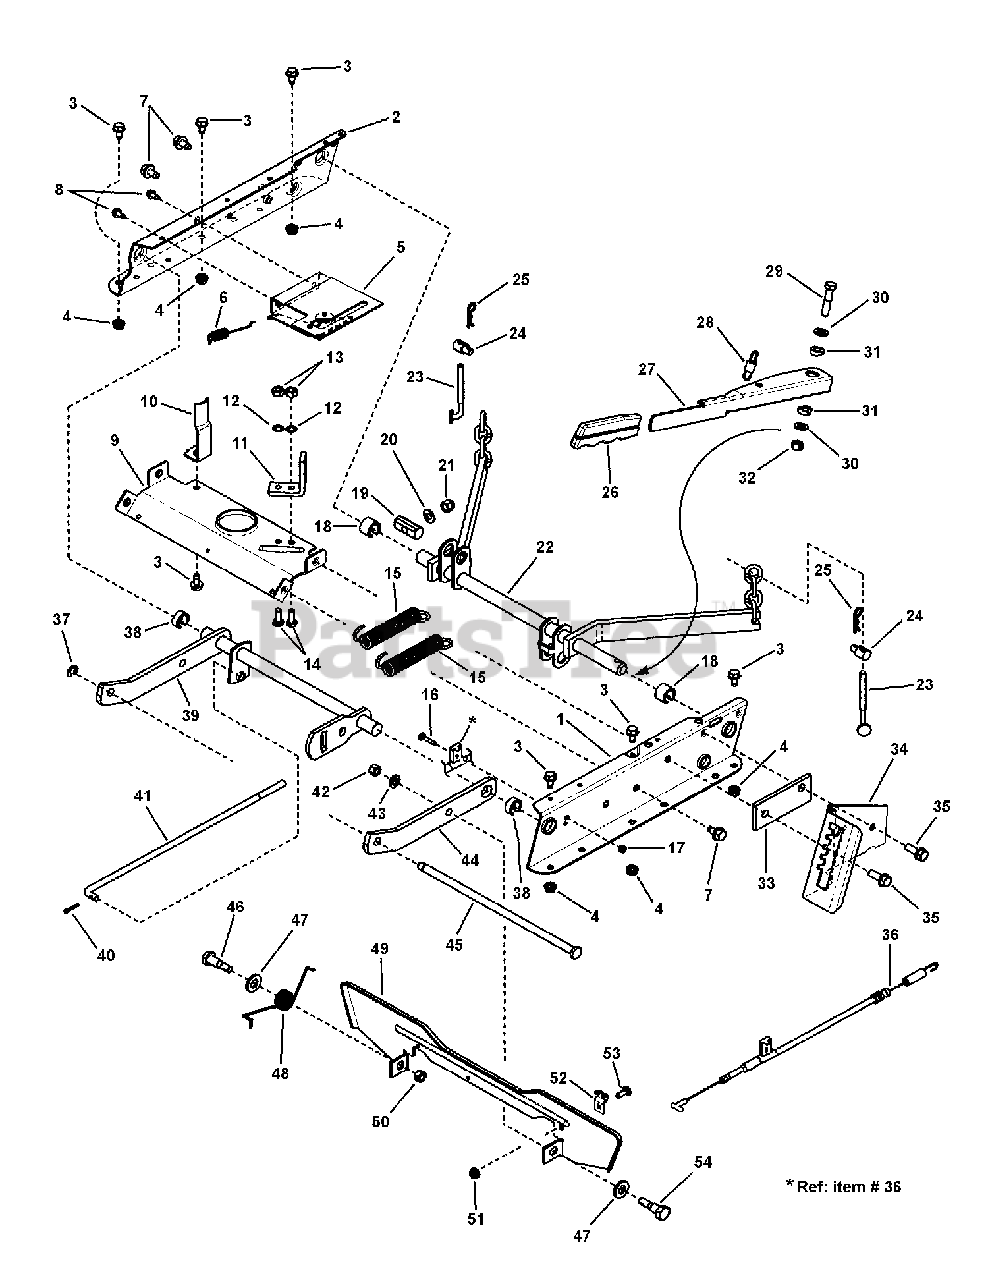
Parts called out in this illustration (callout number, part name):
1	RAIL, Deck Lift, Left Hand
2	RAIL, Deck Lift, Right Hand
3	SCREW, 5/16-18 x 5/8 Hex Washer Self-Tap
4	NUT, Serrated Lock Flange, 5/16-18
5	ASSEMBLY, Clutch Plate
6	SPRING, Latching
7	SCREW, 3/8-16 x 5/8 Hex Washer Self-Tap
8	SCREW, 5/16-18 x 1/2 Hex Washer Self-Tap
9	BRACE, Top
10	GUIDE, Belt
11	ANCHOR
12	WASHER, 5/16, Internal Lock, Zinc/Clear
13	NUT, 5/16-24, GR5, Serated Flange, Zinc/Clear
14	SCREW, 5/16-24 x 3/4 Hex Head Cap, GR 5
15	SPRING, Assist
16	BOLT, #10-24 x 1 Flat Head Square Neck
17	NUT, #10-24, Hex Nylock, GRB, Zinc/Clear
18	RING, Rear Lift Arm (Blue)
19	PIVOT, Leveling
20	WASHER, 3/8 Flat SAE
21	NUT, 3/8-24 Hex Nyloc
22	WELDMENT, Rear Lift Arm
23	ADJUSTER, Chain (5/16-18 thread)
24	SWIVEL, Adjustable
25	HAIR PIN, 3/32 x 1-1/2"
26	GRIP, Height Adjustment Lever
27	LEVER, Height of Cut
28	SPRING, Lever
29	SCREW, 3/8-24 x 1-3/4 Hex Head Cap, GR 5
30	WASHER, 13/32 x 1-1/4 Flat
31	SPACER, Deck Lift
32	NUT, 3/8-24 Hex Center Lock
33	SPACER, Detent
34	DETENT, Height Adjust
35	SCREW, 3/8-16 x 1 Hex Washer Self-Tap
36	CABLE ASSEMBLY, No Reverse in Mow
37	RING, .438 External Retaining
38	RING, Front Lift Arm (Red)
39	WELDMENT, Front Lift Arm
40	PIN, 1/8 x 3/4 Cotter
41	ROD, Leveling (3/4-24 thread)
42	NUT, 3/8-24 Hex, GR B
43	WASHER, Flat 13/32 ID x 1.25 x 1/8 Thick ZP
44	ARM, Front Lift
45	ROD, Deck Support (Front Lift Arm to Front End)
46	SHOULDER BOLT, 3/8-24 x 9/16"
47	WASHER, 1/2 Flat SAE, GRB, Zinc/Clear
48	SPRING, Pedal
49	FOOT PEDAL, Blade Stop Control
50	NUT, 3/8-24 Hex Center Lock
51	NUT, 1/4-20 Hex Flange Lock, GR 5
52	CLIP, Cable
53	BOLT, 1/4-20 x 3/4 Square Neck Carriage, GR 5
54	SHOULDER BOLT, 3/8-24 w/Nylon Patch, GR 5
